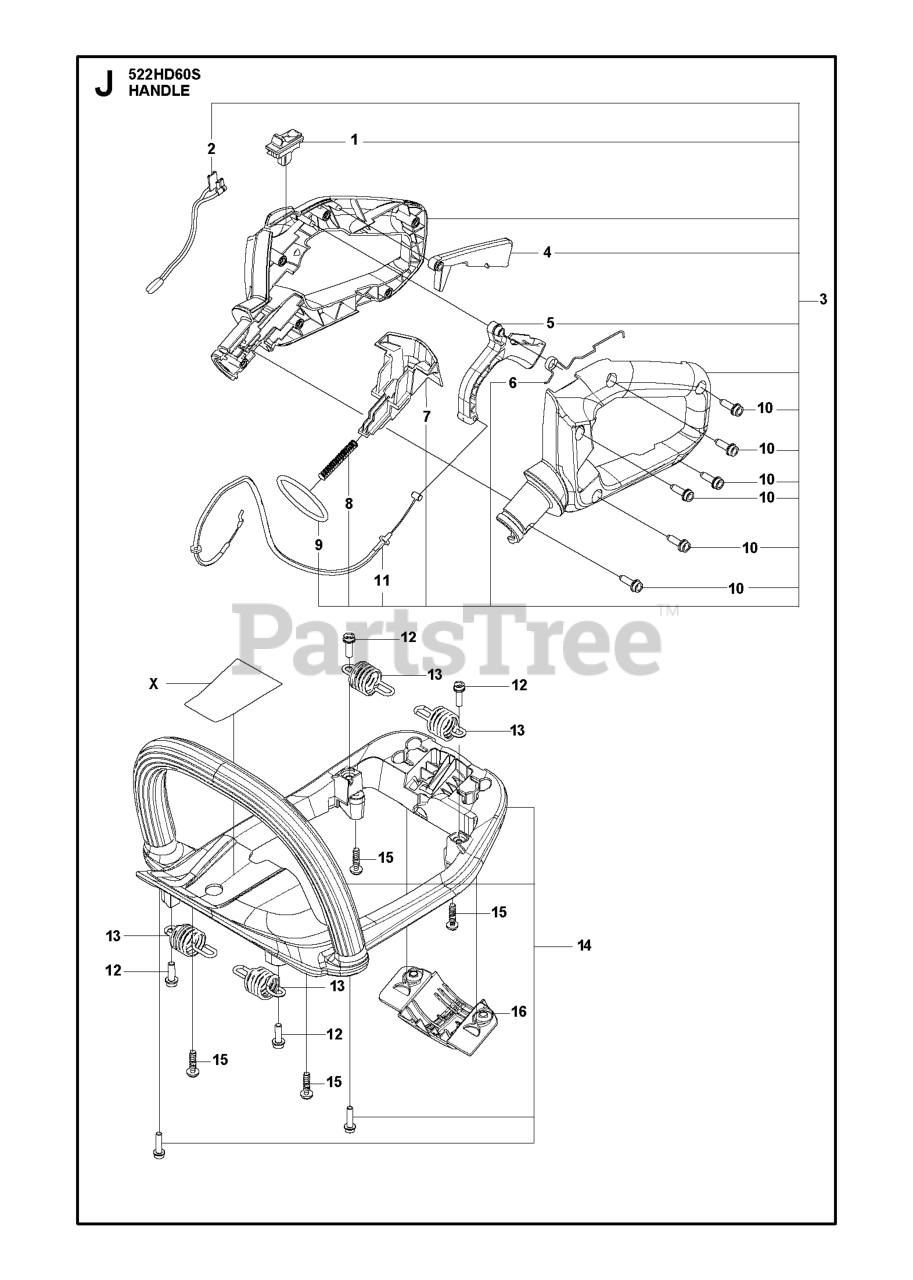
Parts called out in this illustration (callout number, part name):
1	STOP BUTTON
2	SHORT CIRCUIT CABLE HANDLE A05
3	REAR HANDLE KIT 522HD60
4	THROTTLE LOCKOUT HUSQVARNA ORA
5	THROTTLE CONTROL HUSQVARNA-OR
6	SPRING HANDLE
7	LOCKING BUTTON HUSQVARNA-ORAN
8	RECOIL SPRING
11	THROTTLE CABLE ASSY HD
13	SPRING ANTI-VIBRATION
14	FRONT HANDLE ASSY 522HD60
16	PROTECTION ASSY HUSQVARNA-GREY
